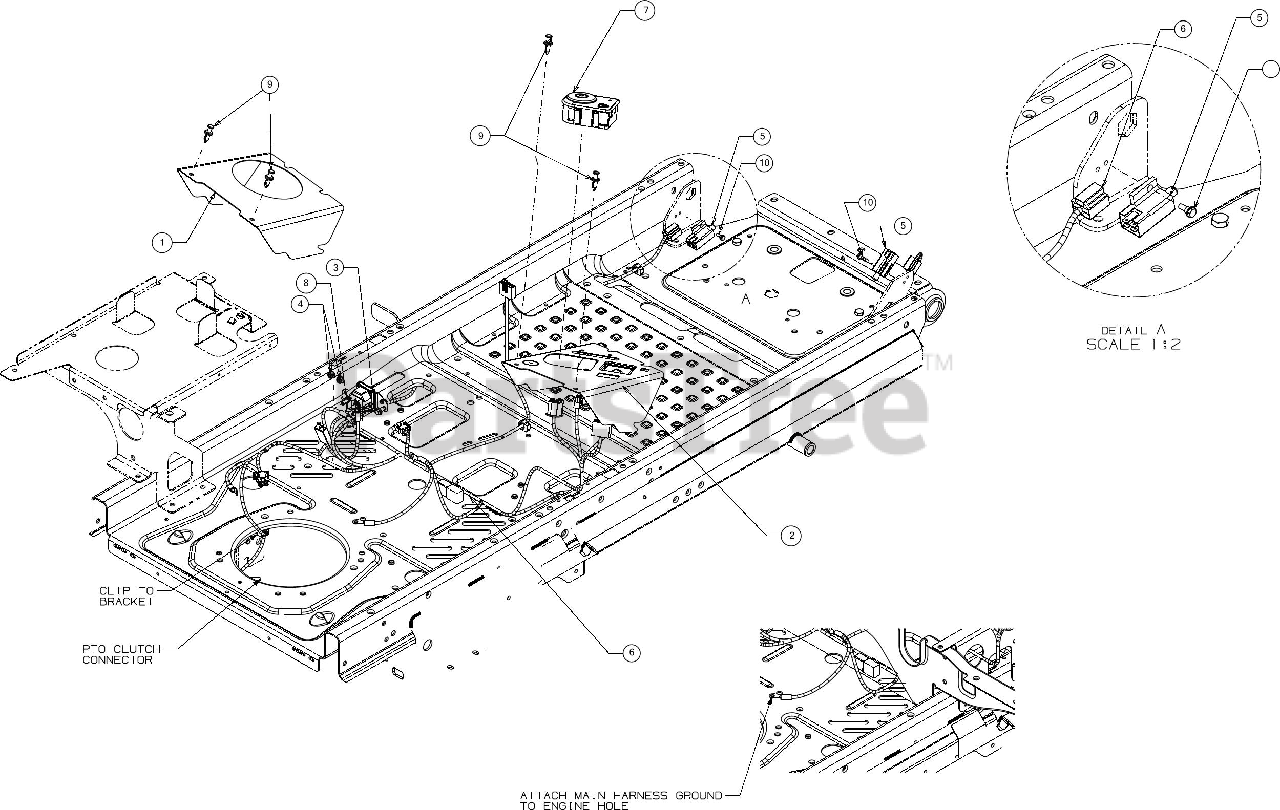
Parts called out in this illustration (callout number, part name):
1	CONSOLE COVER (LH)
2	CONSOLE COVER (RH)
3	SCREW 1/4-20X.625
4	FLANGE LOCK NUT
5	INTERLOCK SWITCH (NO/NC)
6	MAIN HARNESS (RMC)
7	IGNITION MODULE SWITCH RMC (ELC PTO WHTE)
8	SOLENOID-12V 100A
9	PLASTIC RIVET
10	SHOULDER SCREW
